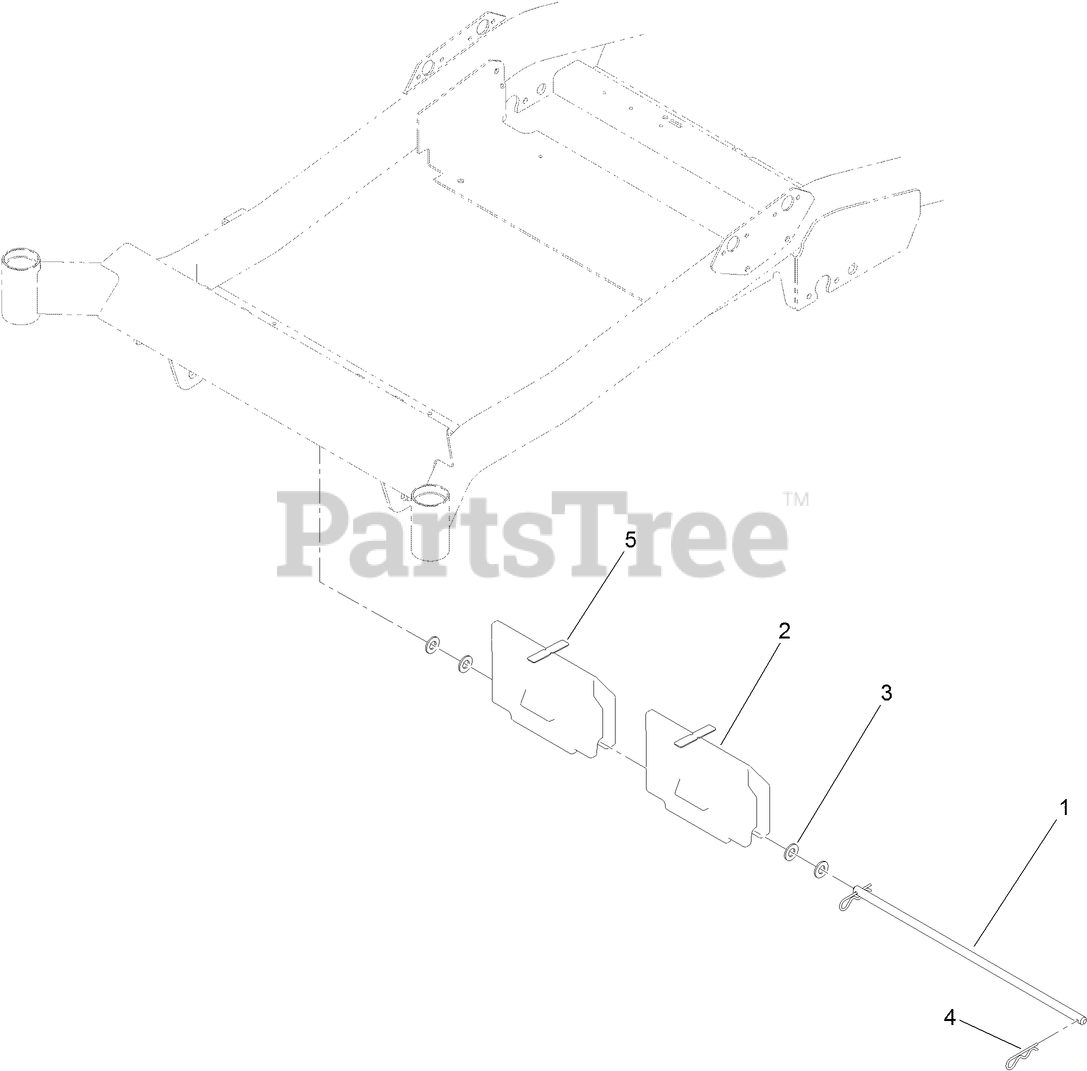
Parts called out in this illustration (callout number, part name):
1	ROD-DECK, PIVOT
2	WEIGHT-BAGGER
3	WASHER-FLAT
4	PIN-HAIR
5	BUMPER-PAD
